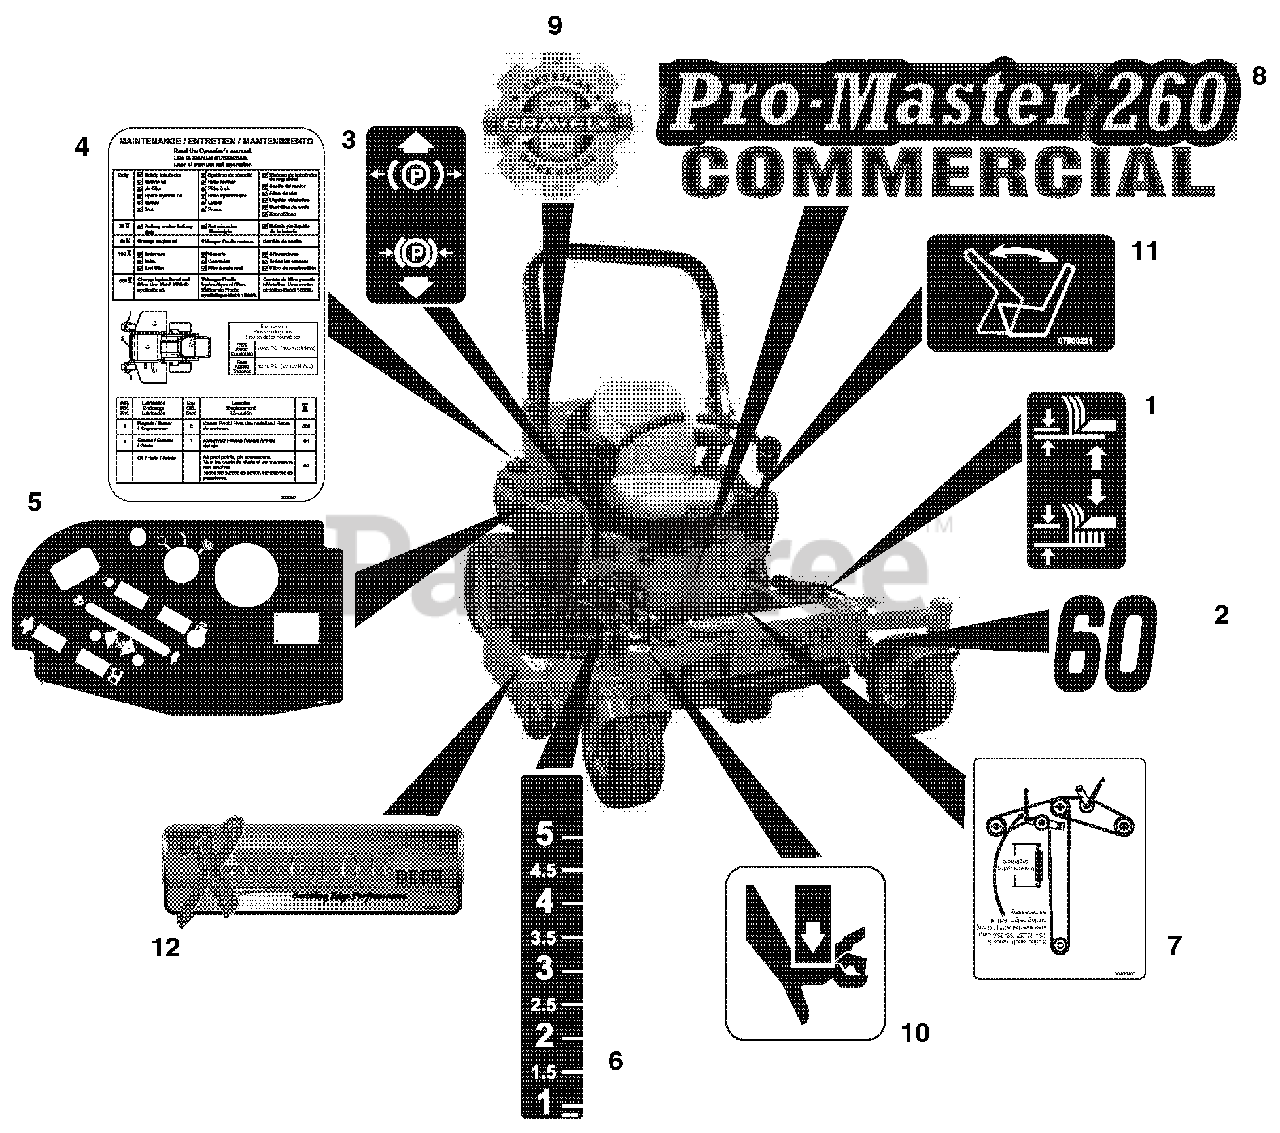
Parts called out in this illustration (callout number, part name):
1	Decal, Lift Lever
2	Decal, 60"
3	Decal, Parking Brake Lever
4	Decal, Maintenance Instructions
5	Decal, Diesel Control Panel
6	Decal, Height of Cut
7	Decal, Belt Routing
8	Decal, Pro-Master 260
9	Decal, Gravely Heritage – Large
10	Decal, Pinch Point
11	Decal, Seat Release
12	Decal, X-Factor Deck
